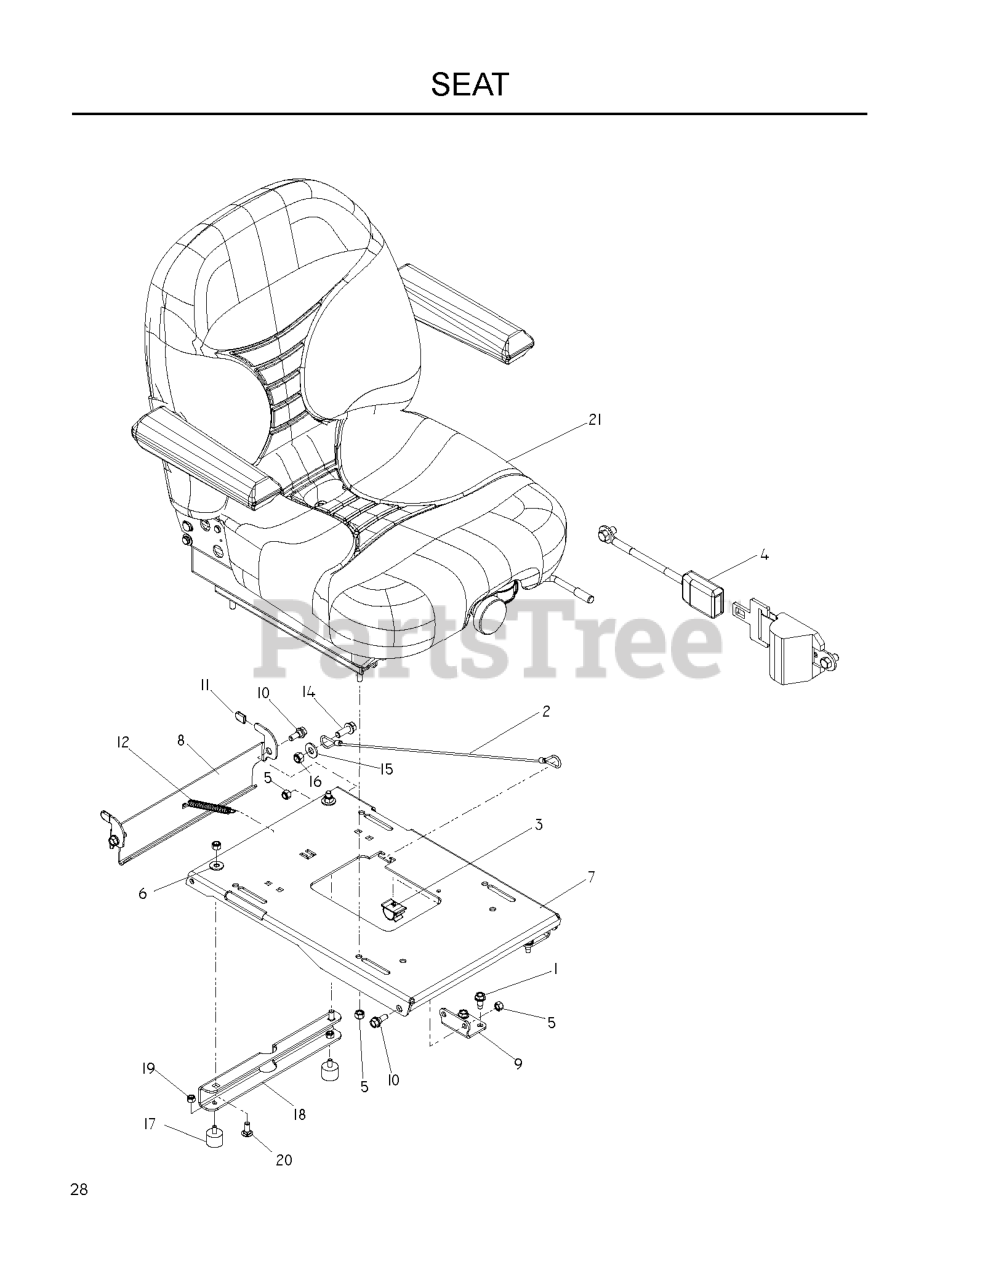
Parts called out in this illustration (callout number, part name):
1	BOLT 5/16-18 X 3/4
2	SEAT LANYARD
3	PUSH-MOUNT WIRE CLIP
4	SEAT BELT, RETRACTABLE
5	NUT 5/16 NYLOC
6	WASHER 5/16 FLAT
7	PAN, SEAT - BLACK
8	LATCH, SEAT - BLACK
9	PIVOT, SEAT PAN
10	SB 5/16-18 HEX HD GD5, BLK ZN
11	GRIP, VINYL, .09 X .495 X.75
13	HCS 5/16C X 1
14	4CS 3/8C X 1 SERRATED HEAD
15	WASHER 3/8 FLAT
16	NUT 3/8-16 NYLOC
17	STUD/PLATE MOUNT
18	STANDOFF, SEAT PAN
19	NUT.1/4-20.HEX.NYLOC.ZD
20	BOLT 5/16C X 3/4" CARRIAGE
21	SEAT - SUSP, NC SWITCH
21	SEAT for units produced before Serial No. 074439861
